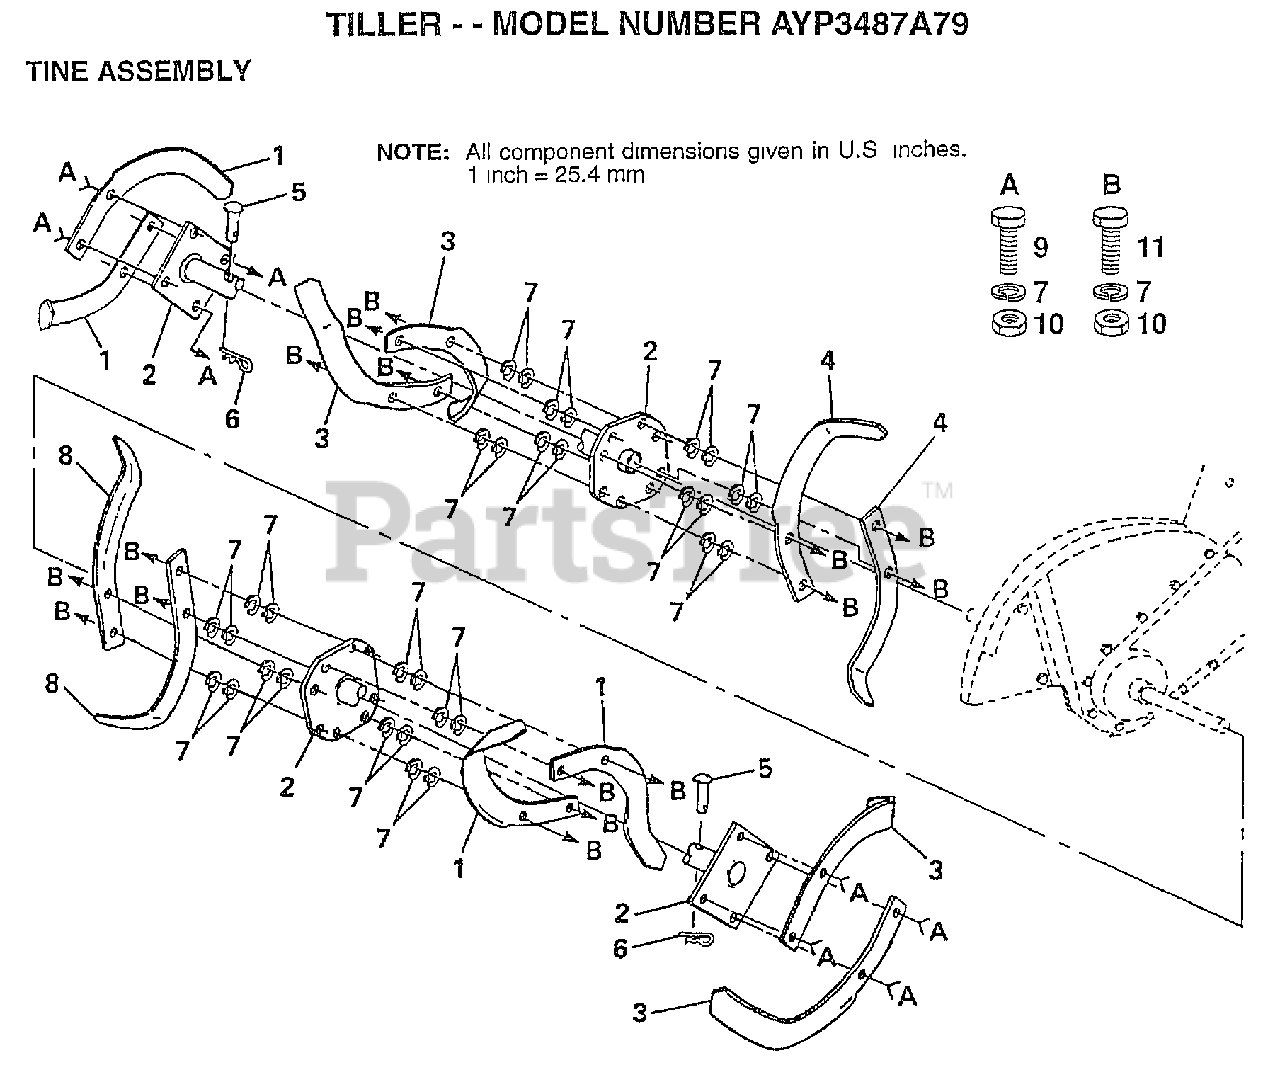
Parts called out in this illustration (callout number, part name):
2	TINE ASSY CRT
4	TINE.LH.CRT
5	RIVET.PAN HD.1.75
6	RETAINER.SPRING
7	LOCKWASHER
8	TINE RH CRT
9	BOLT
11	BOLT.3/8-24X1-1/2
